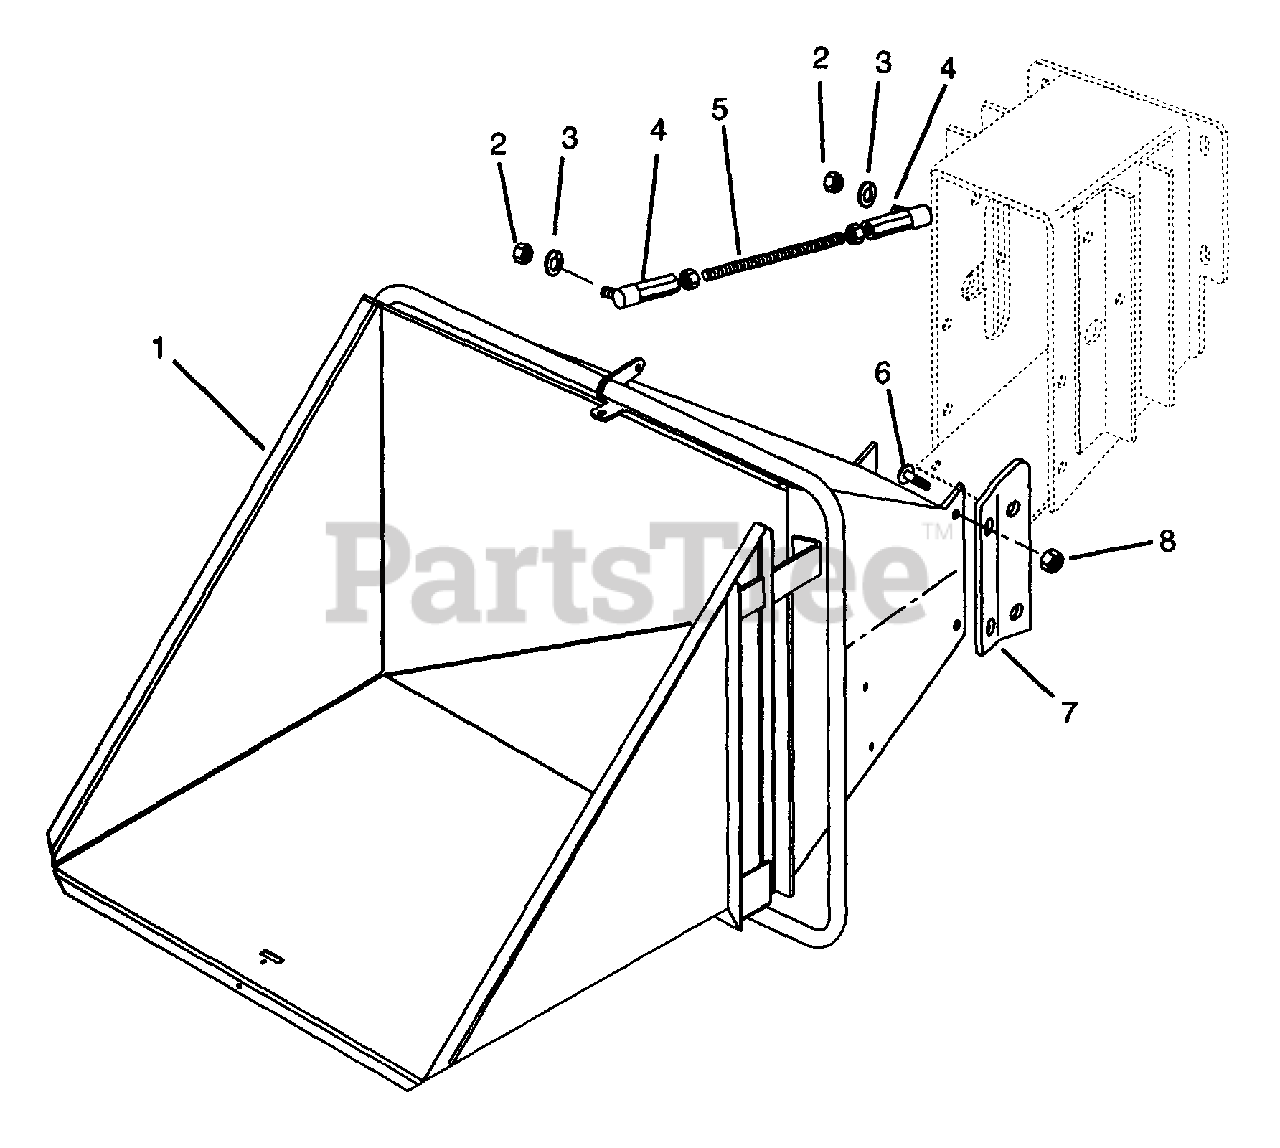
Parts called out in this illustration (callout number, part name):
1	Package-Hopper Repair
2	Nut-Jam .312-24
3	Washer-Lock .312
4	Ball Joint
5	Rod, Threaded
6	Screw, Socket-Button Head .38-16 x 1.00
7	Hopper Support-Left Hand
7	Hopper Support-Right Hand
8	Nut-Locking-Top .375-16
